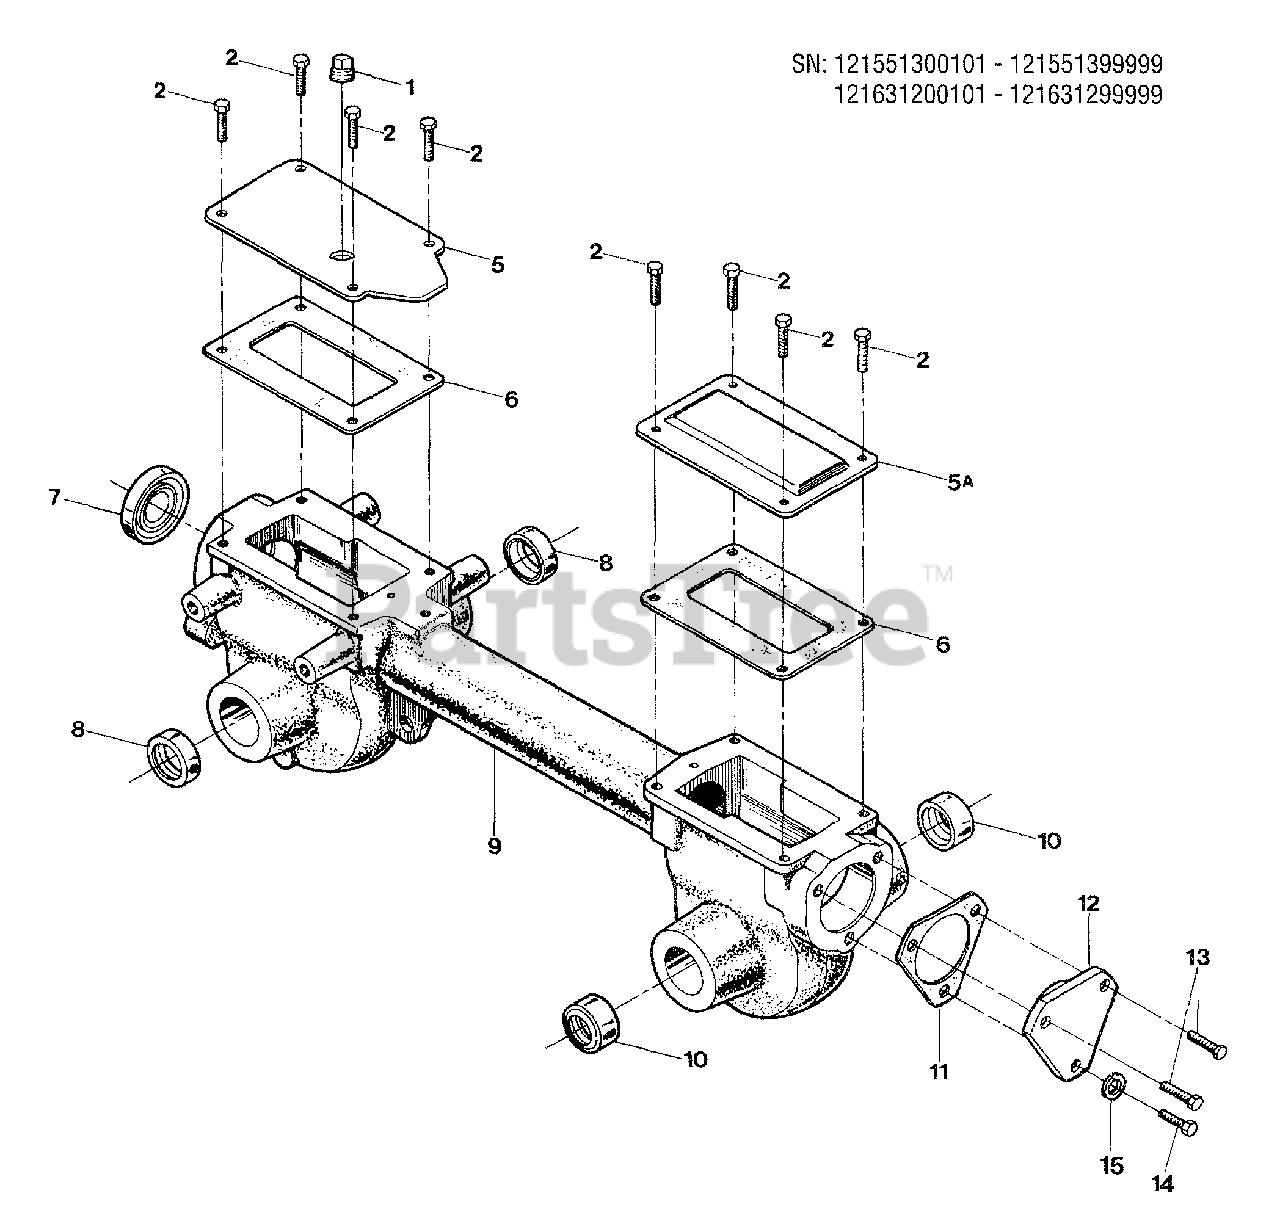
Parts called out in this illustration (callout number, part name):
1	Plug-Transmission Oil Fill/Check
2	Bolt-Hex Hd., Flange Lock, 5/16-18 x 5/8", GR5
5	Cover-Trans. Housing Front
5A	Cover-Trans. Housing, Rear
6	Gasket-Transmission Housing Cover (Front and Rear)
7	Oil Seal-Drive Shaft
8	Oil Seal-Wheel Shaft
9	Transmission Case, Rear Housing and Tube Assembly
10	Oil Seal-Tine Shaft
11	Gasket-Bearing Cap (.010" thick)
12	Cap-Rear Bearing
13	Bolt-Flanged Hd., 5/16-18 x 1"
14	Bolt-Flanged Hd., 5/16-18 x 3/4"
15	Lockwasher, 5/16"
